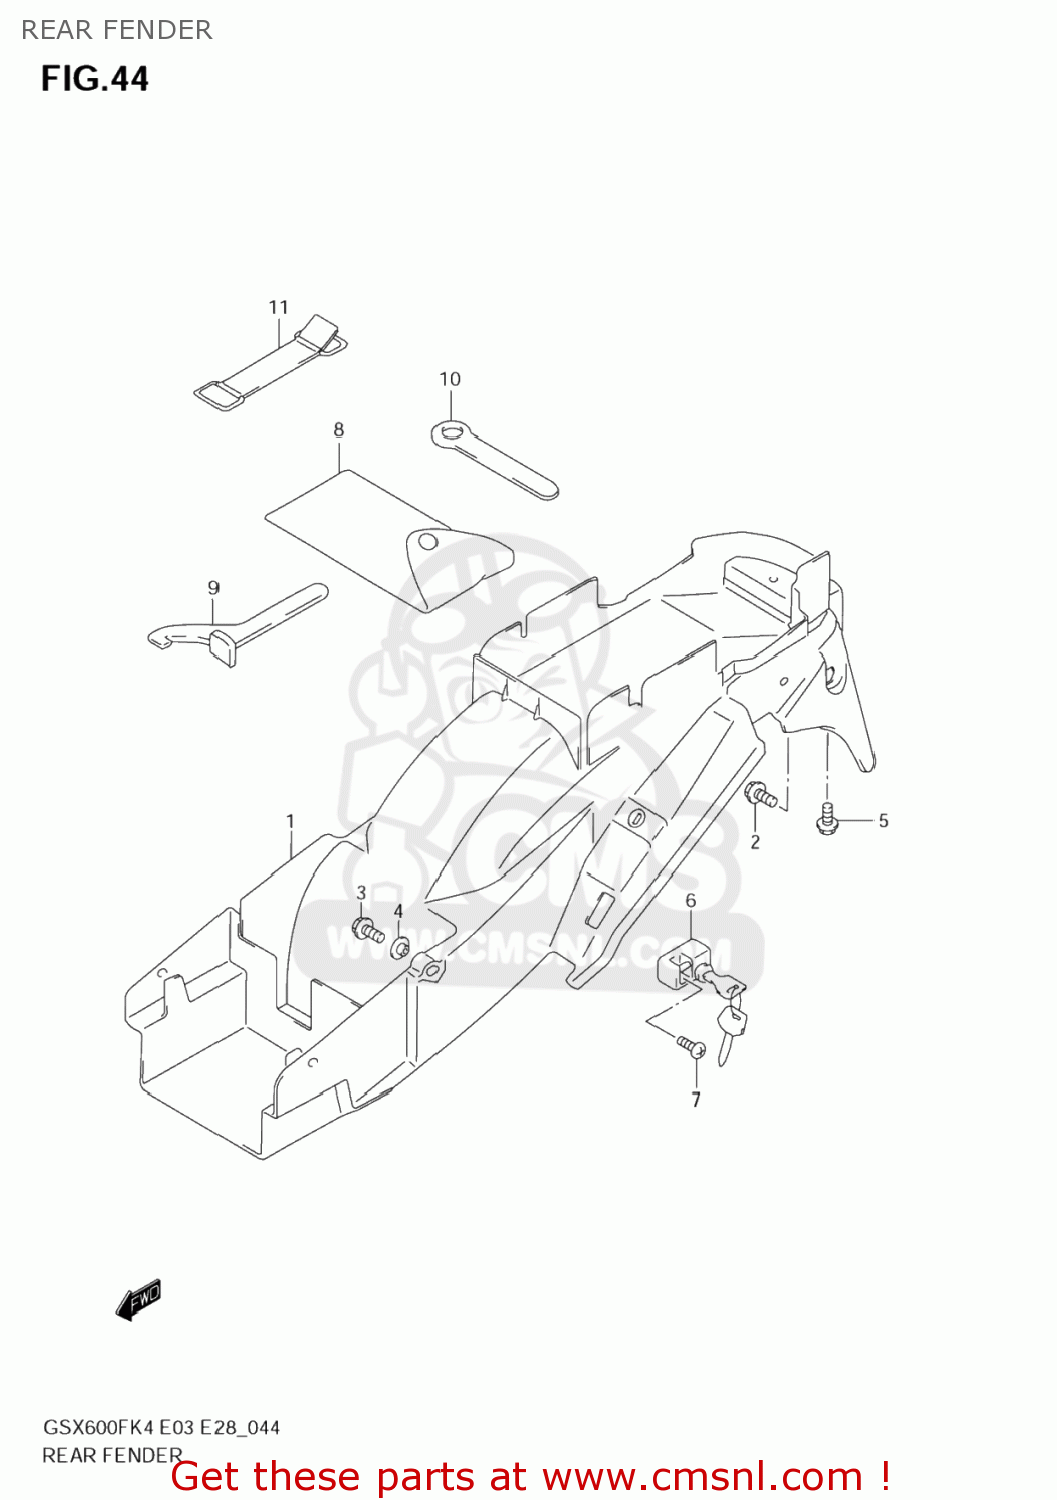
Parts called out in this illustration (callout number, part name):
1	FENDER,RR
2	BOLT(6X16)
3	BOLT
4	WASHER
5	BOLT(6X16)
6	LOCK SET,HELMET
7	SCREW(6X14)
8	TOOL ASSY
9	CLAMP
10	SPANNER,HEXAGON
11	BAND,TOOL
